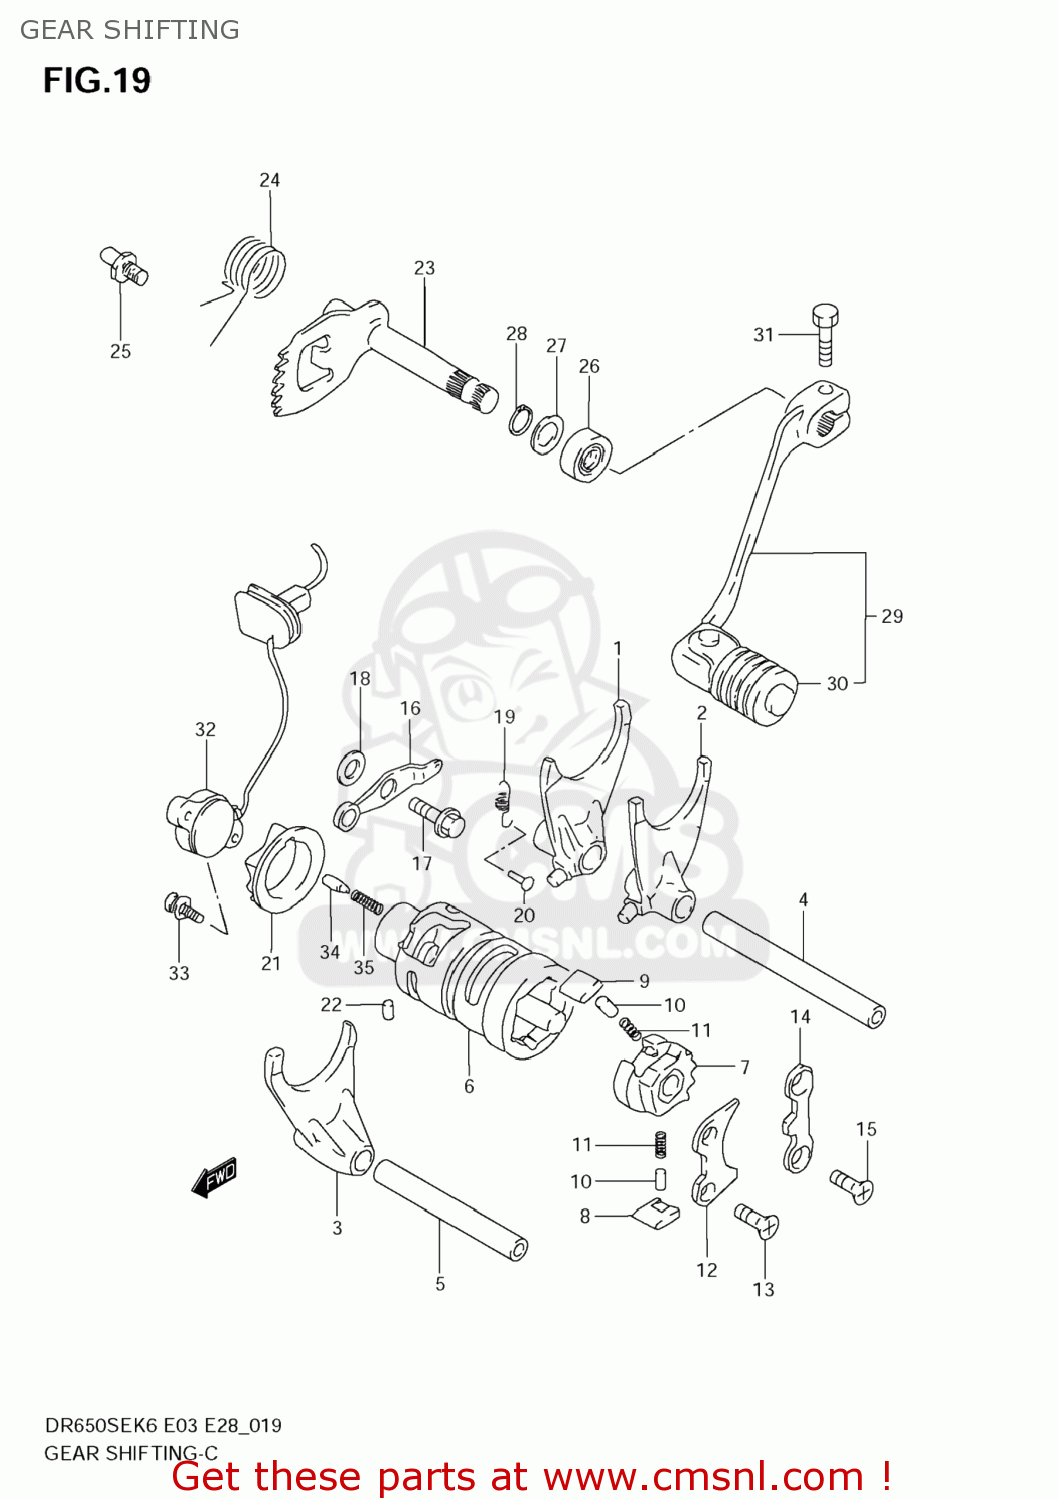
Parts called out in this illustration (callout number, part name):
1	FORK,GEAR SHIFT NO.1
2	FORK,GEAR SHIFT NO.2
3	FORK,GEAR SHIFT NO.3
4	SHAFT,GEAR SHIFT FORK
5	SHAFT,GEAR SHIFT FORK
6	CAM,GEAR SHIFT
7	GEAR,GEAR SHIFT CAM DRIVEN
8	PAWL,GEAR SHIFT NO.1
9	PAWL,GEAR SHIFT NO.2
10	PIN(5X8)
11	SPRING
12	LIFTER,GEAR SHAFT PAWL
13	SCREW(6X12)
14	STOPPER,GEAR SHIFT POLE
15	SCREW(6X12)
16	STOPPER,GEAR SHIFT CAM
17	BOLT(6X14.6)
18	WASHER
19	SPRING
20	RIVET
21	PLATE,GEAR SHIFT CAM STOPPER
22	PIN
23	SHAFT,GEAR SHIFT
24	SPRING
25	STOPPER,GEAR SHIFT ARM
26	OIL SEAL
27	WASHER
28	CIRCLIP
29	LEVER ASSY,GEAR SHIFT
30	RUBBER,GEAR SHIFT PEDAL
31	BOLT
32	BASE ASSY,NEUTRAL SW TERMINAL
33	SCREW
34	PIN(5X15.5)
35	SPRING
